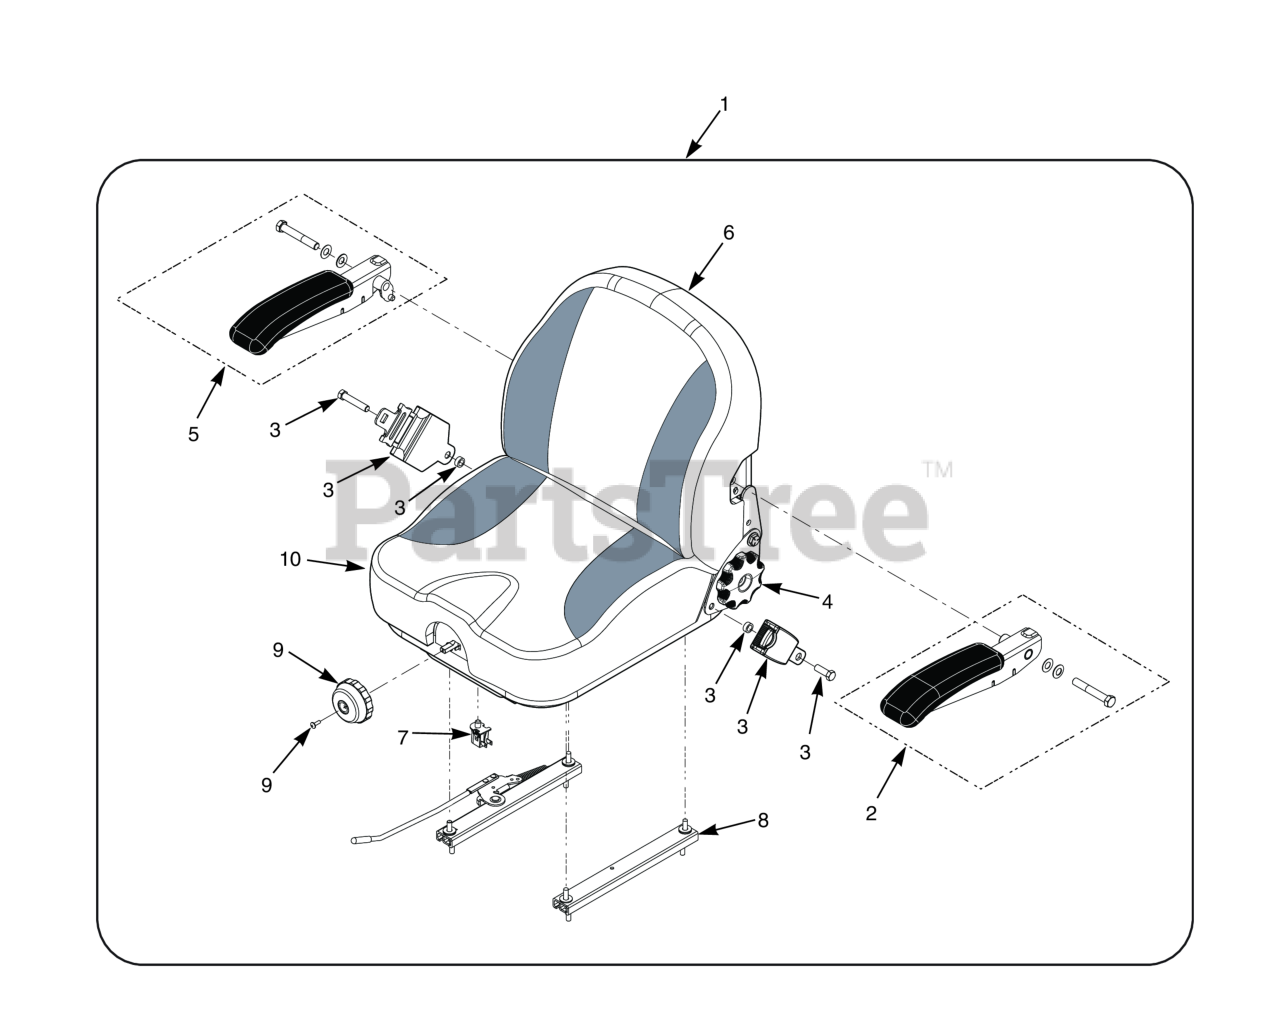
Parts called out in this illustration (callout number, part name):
1	Suspension Seat Assembly w/seat belt
2	Armrest Kit, LH
3	Seat Belt Kit (Suspension Seat)
4	Knob Kit, Recliner
5	Armrest Kit, RH
6	Cover, Back Cushion
7	Switch, Interlock, Normally Open
8	Track Kit
9	Knob Kit, Weight Adjust
10	Cover, Seat Cushion
